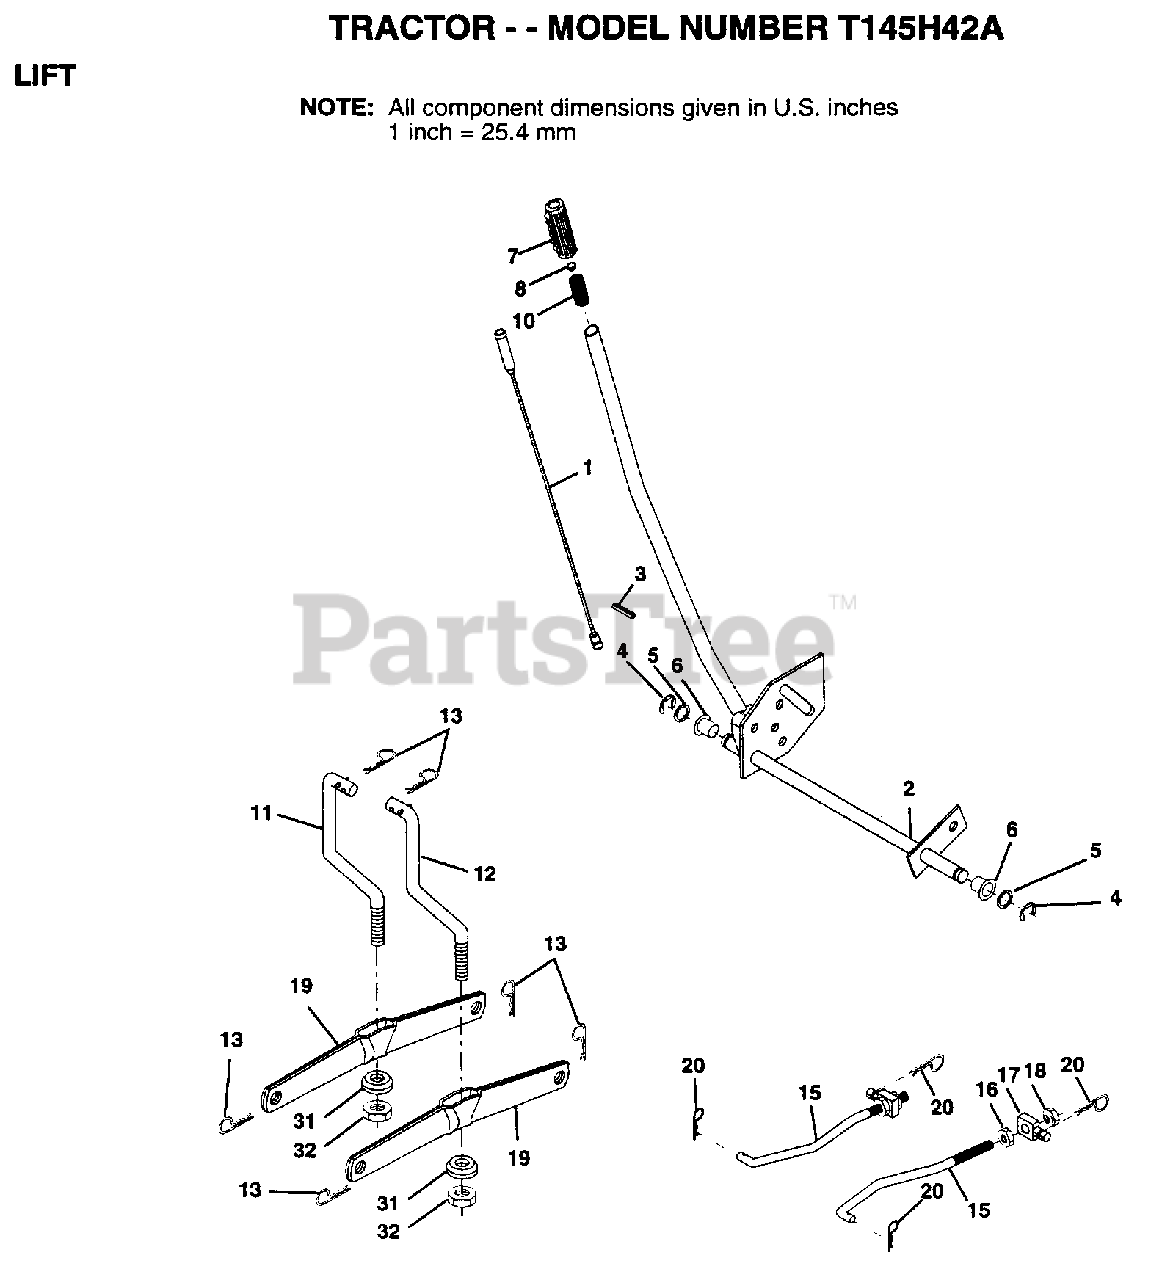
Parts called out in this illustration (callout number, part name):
1	WIRE ASM
2	HANDLE.LIFT.LH.
3	PIN GROOVE
5	WASHER
6	NYLON BEARING
7	GRIP
15	LINK.FRONT
16	NUT
17	TRUNION
18	NUT.LK.W/WSH.1/2.
19	ARM SUSP REAR
20	RETAINER.SPRING
31	BEARING PVT LH
32	NUT.CROWNLOCK.3/8
